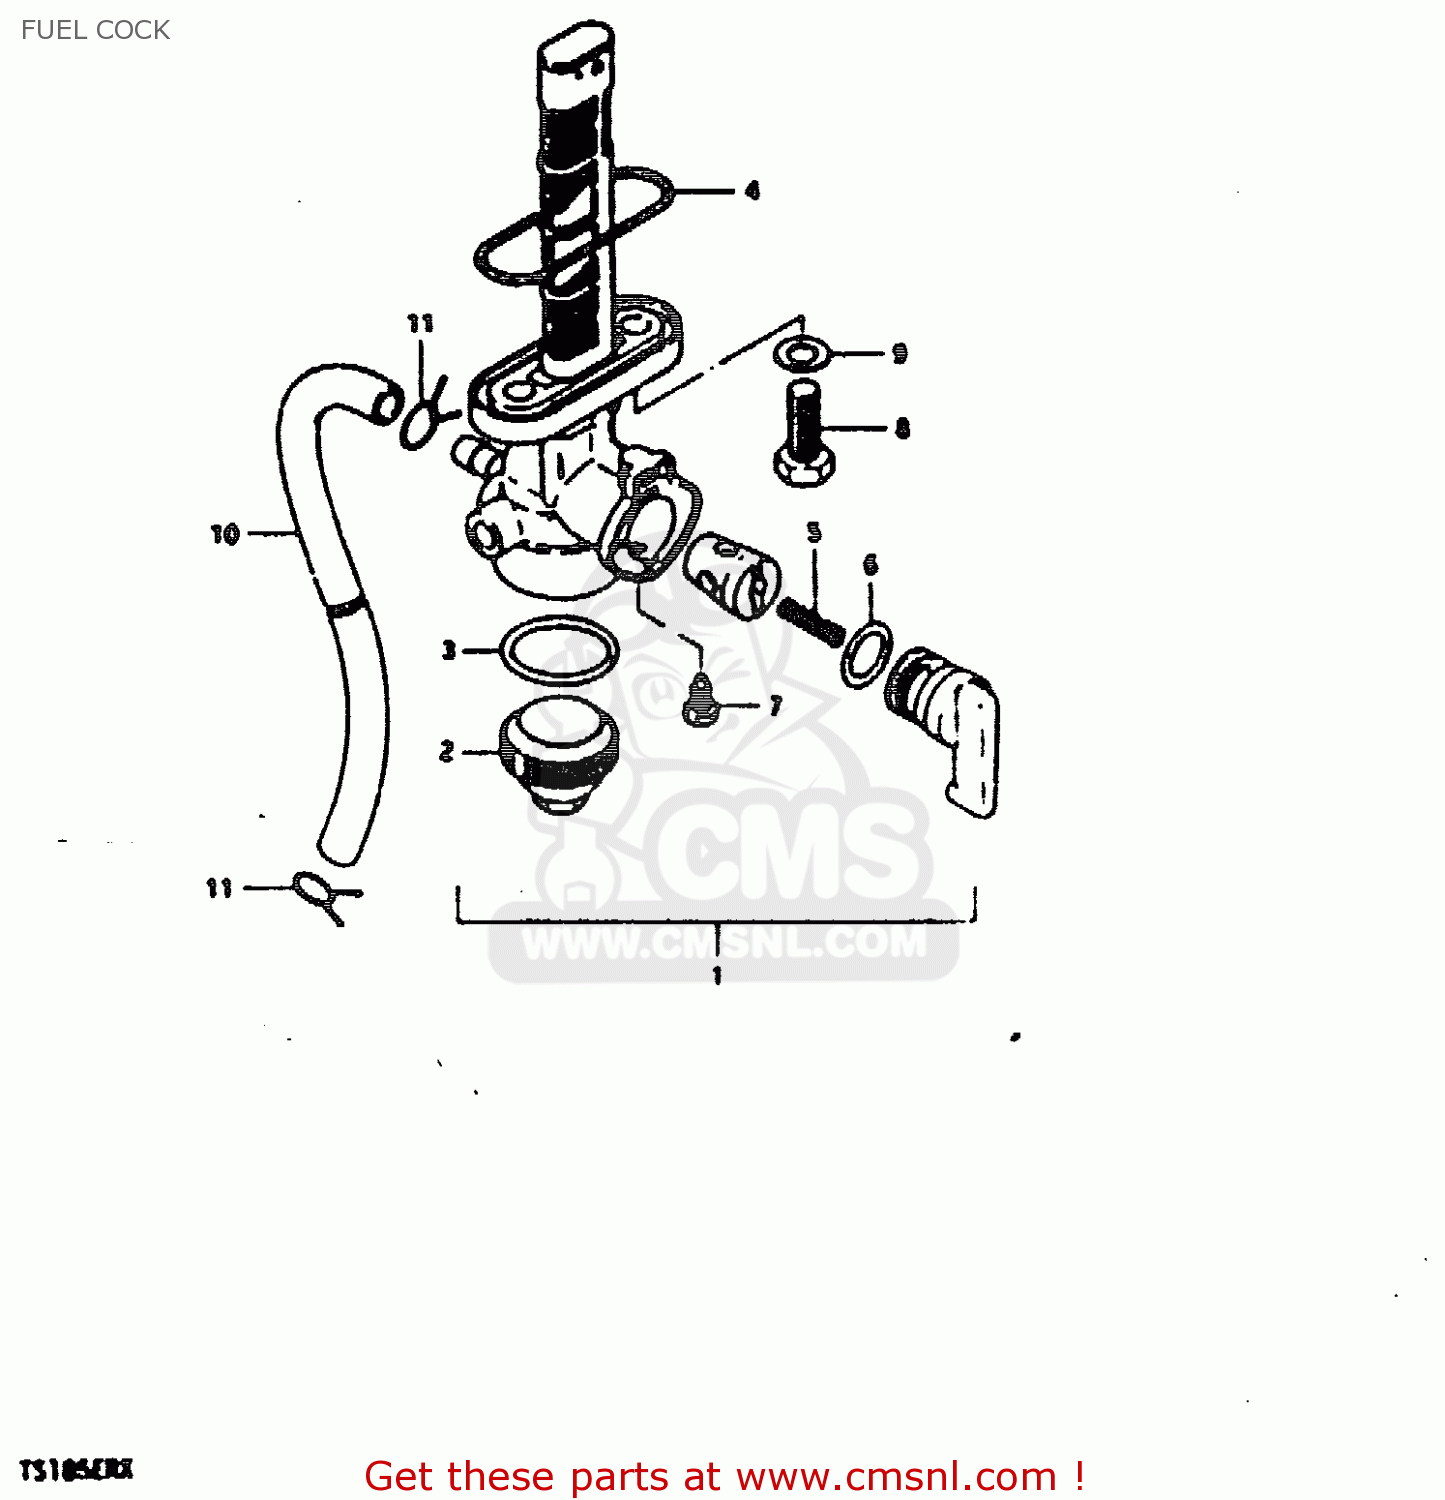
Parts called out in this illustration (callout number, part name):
1	COCK ASSEMBLY,FUEL
2	CUP,STRAINER
3	GASKET,FILTER (NAS)
4	O RING,FUEL COCK
5	SPRING
6	O-RING
7	SCREW
8	BOLT(6X20)
9	GASKET
10	HOSE
11	CLIP
